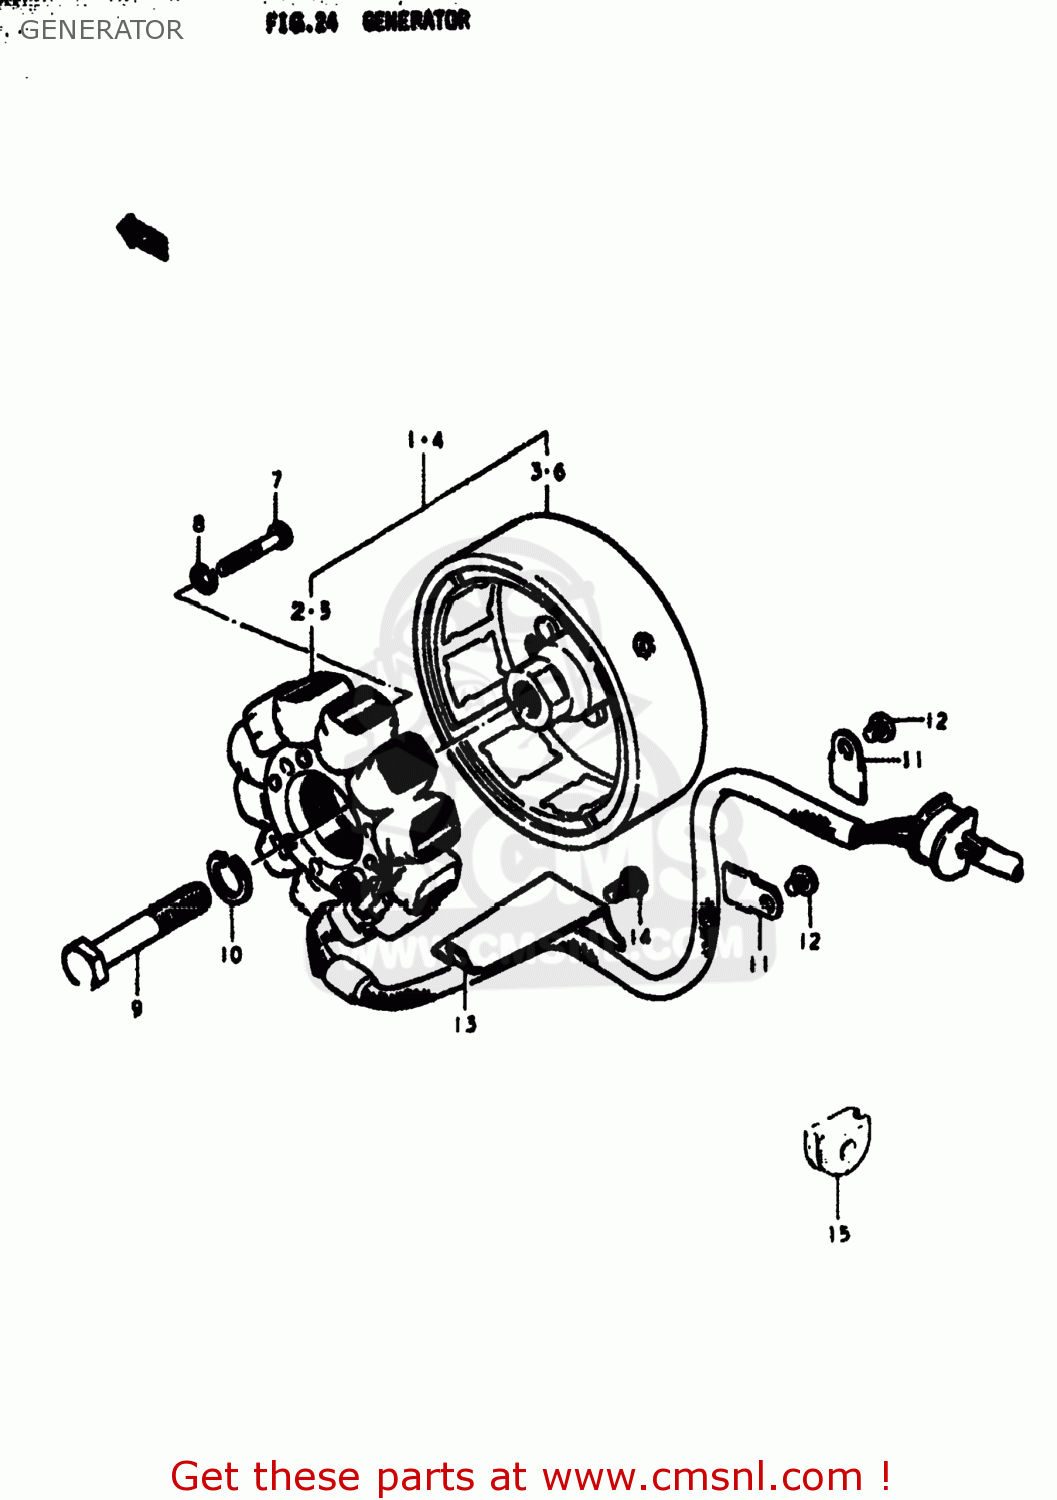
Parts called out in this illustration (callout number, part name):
1	GENERATOR ASSEMBLY
2	STATOR ASSEMBLY
3	ROTOR ASSEMBLY
4	GENERATOR ASSEMBLY
5	STATOR ASSEMBLY
6	ROTOR ASSEMBLY
7	SCREW
8	LOCK WASHER
9	BOLT 12X45
10	WASHER,LOCK 12
11	CLAMP,GENERATOR LEAD WIRE
12	SCREW
13	CLAMP,GENERATOR LEAD WIRE
14	SCREW
15	GROMMET,STARTER CABLE
